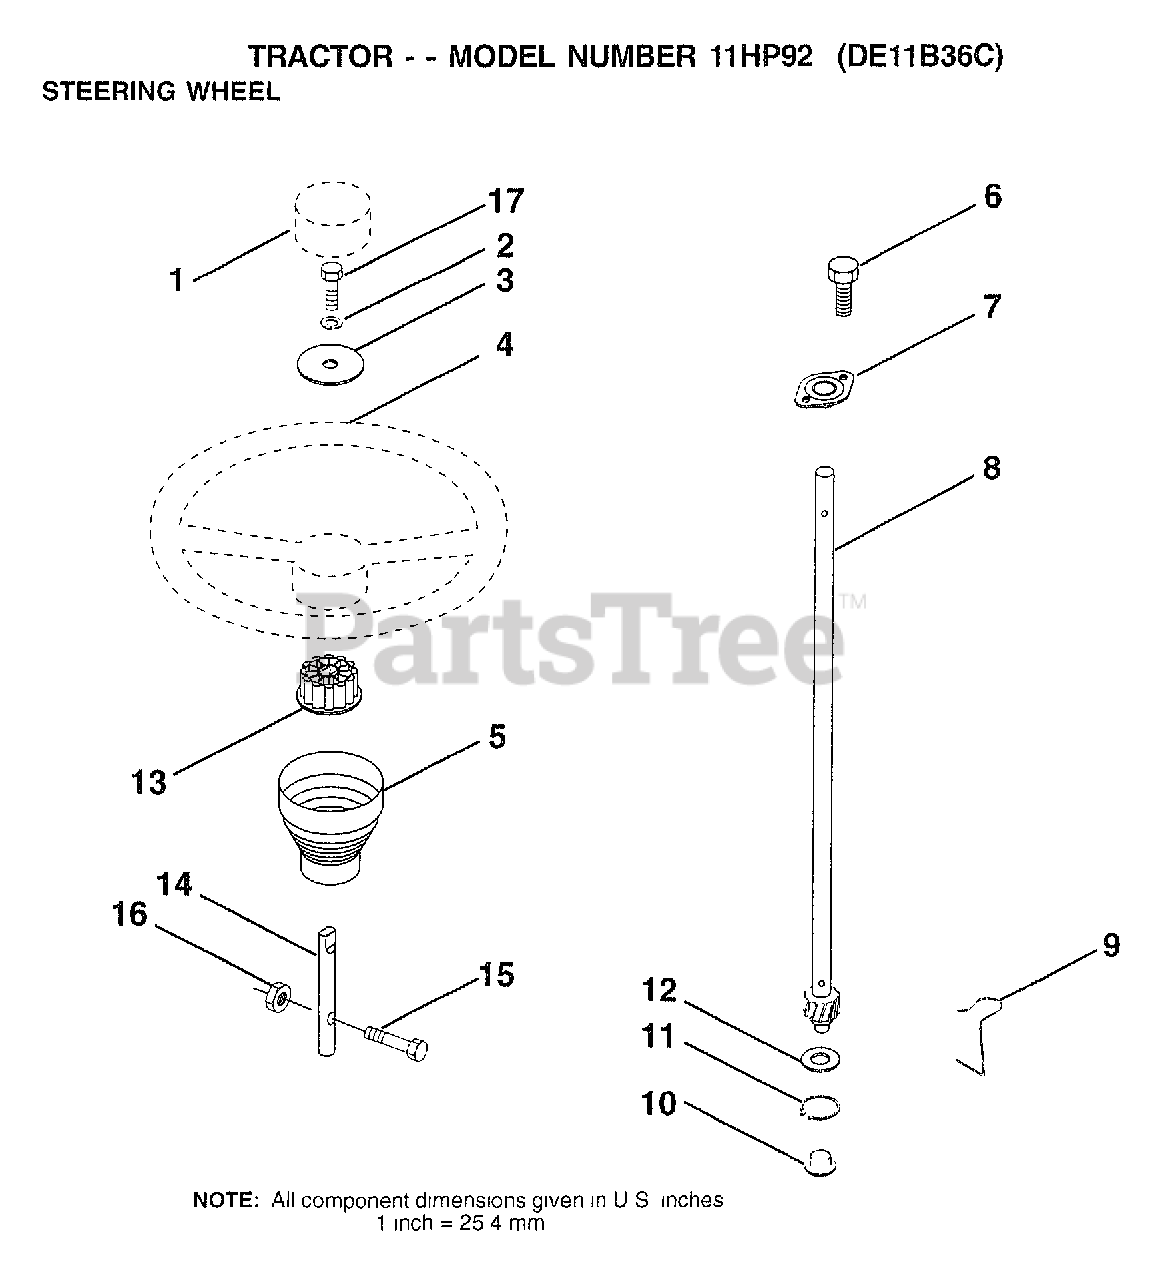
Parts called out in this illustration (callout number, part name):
1	CAP WHEEL STEER
2	LOCKWASHER
3	WASHER T
5	SLEEVE STEERING
6	"SCREW-TT,10-32 FL"
7	BUSHING.STR.623
8	SHAFT.STEERING.LR
9	STEERING CLIP
10	BUSHING STEER LWR
11	RING
12	WASHER LT
13	ADAPTER LT
14	EXT SHAFT STEERIN
15	BOLT
16	NUT
17	BOLT
